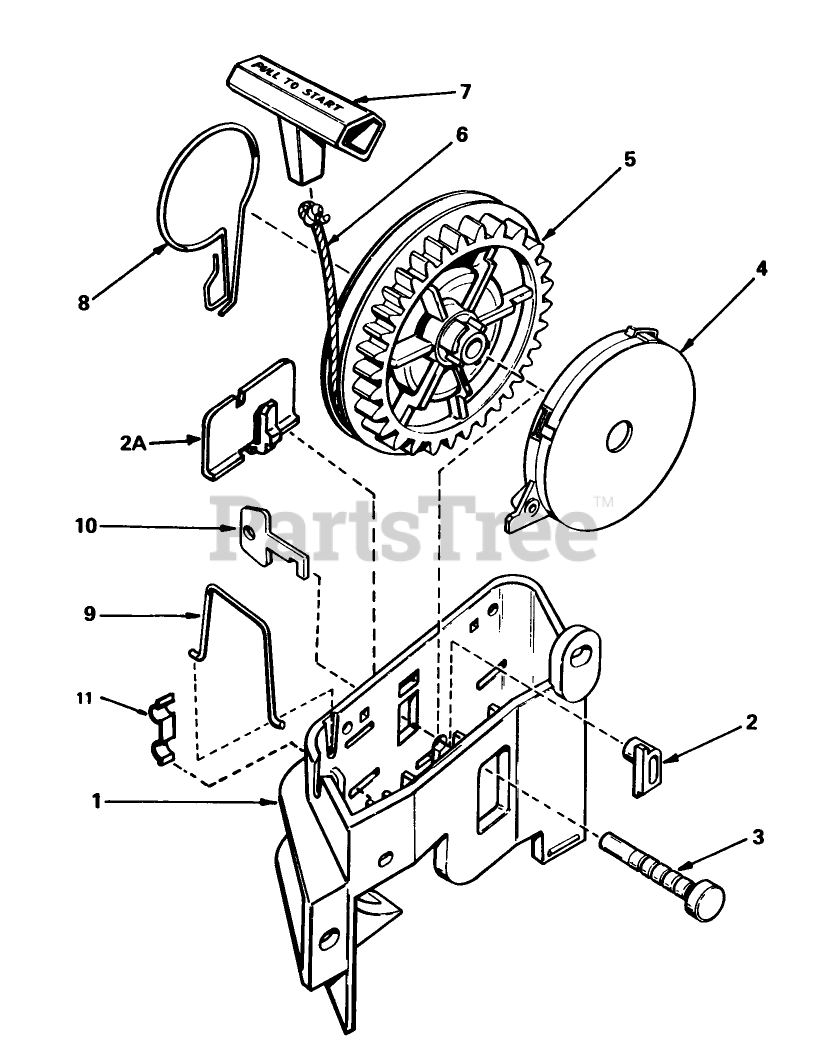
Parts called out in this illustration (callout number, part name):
1	Bracket Starter
2	Pawl, Locking Not used on all engine models)
2A	Clip, Starter Bracket (Used On Starters Not Equipped With Pawl, Ref. No. 2)
3	Pin-Pulley
4	Spring Assy., Rewind (Incl. Ref. #3)
5	Pulley
6	Rope Starter (Length 65" 9/64" Dia.)
7	Handle-Starter
8	Brake
9	Clip-Rope
10	Key (Not Used On All Engine Models
11	Washer-Thrust
